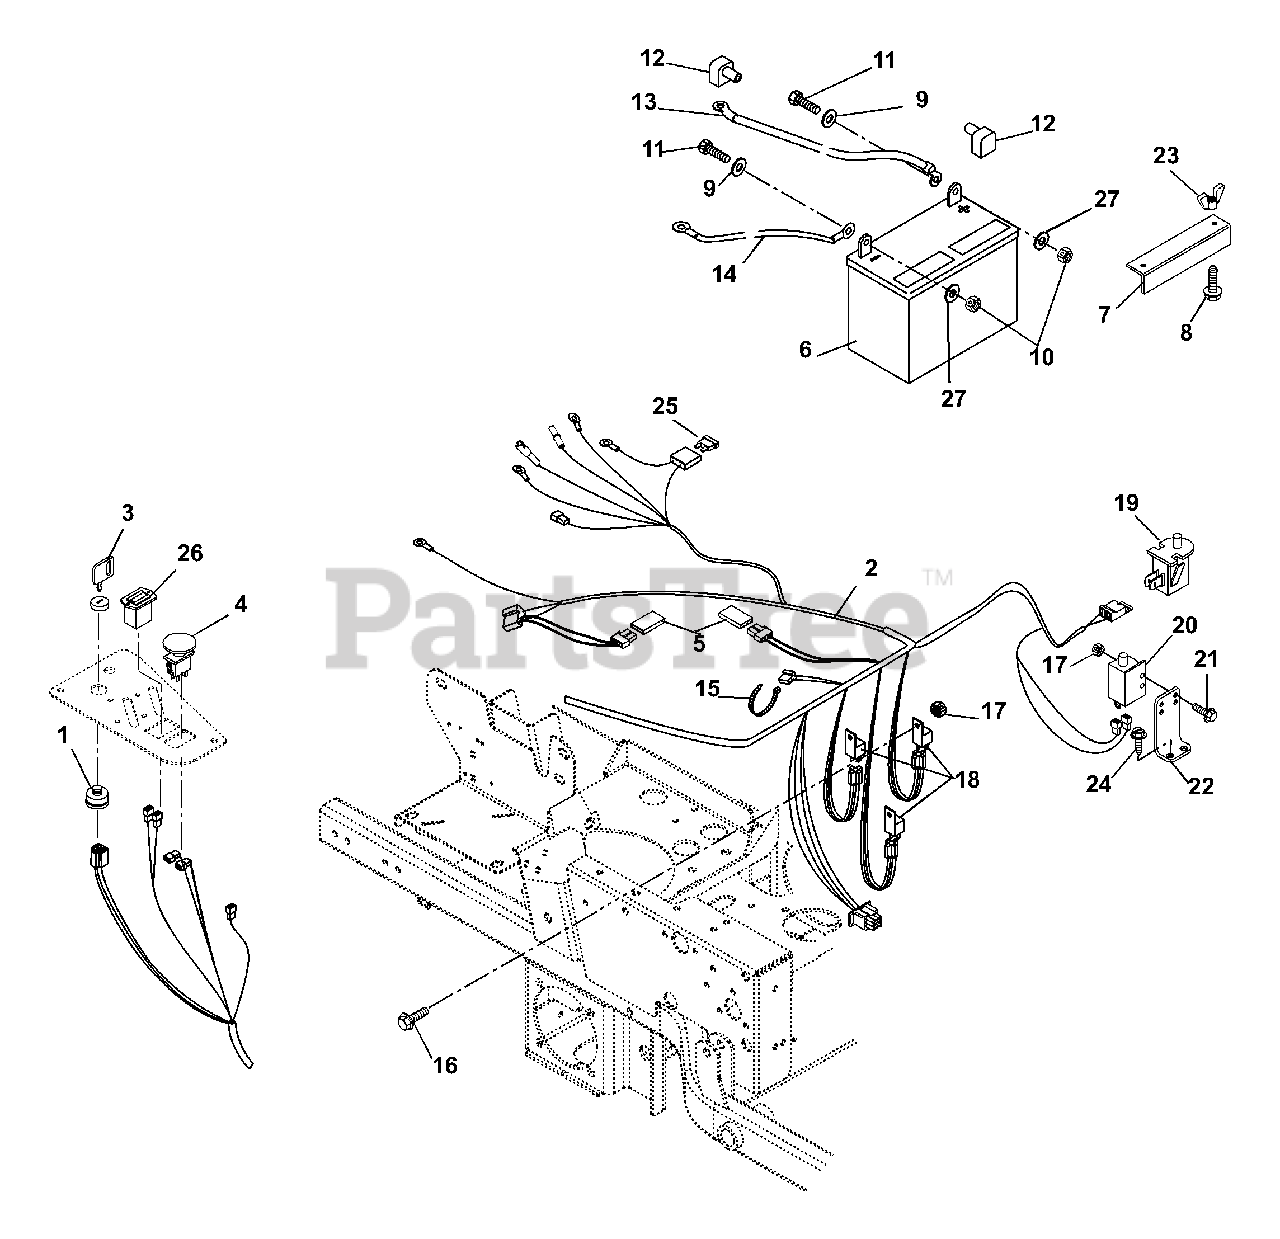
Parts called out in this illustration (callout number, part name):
1	SWITCH, IGNITION
2	HARNESS, IZ & MONST. EYE-Q
3	KEY, W/ SHIELD
4	SWITCH, CLUTCH
5	DIODE, CONNECTOR SHELL
6	BATTERY, 300 CCA 10U1L
7	HOLD DOWN
8	BLT-RDHDSQNK .25-20X7.50 GR2YZ
9	@WSHR-FL-STL.281X.62X.065 YWZC
10	@NUT-HEX .25-20 YWZC
11	@BLT-HEX .25-20X.75 GR5 YWZC
12	INSULATOR
13	CABLE, POSITIVE BATTERY 26.00
14	CABLE-NEGATIVE BATTERY 24.00"
15	CABLE TIE LG 5-1/2
16	@SCR-MCH 10-24X.50 HWH YWZC
17	@NUT-LK-NYL 10-24 W/INSRT YWZC
18	RELAY,SEALED W/DIODE
19	SWITCH- SNAP MTG N.O.
20	SWITCH- SINGLE POLE N.O.
21	@SCR-MCH 10-24X.75 HWH YWZC
22	BRAKE SWITCH MOUNT - BLACK
23	NUT-LK WING .250-20 YWZC
24	@SCR-TAP .25-20X.50 HWH TR YWZ
25	FUSE, 30 AMP.
26	HOURMETER-QUARTZ 80VDCMAX
27	@WSHR-LK .25X.062 REG YWZC
